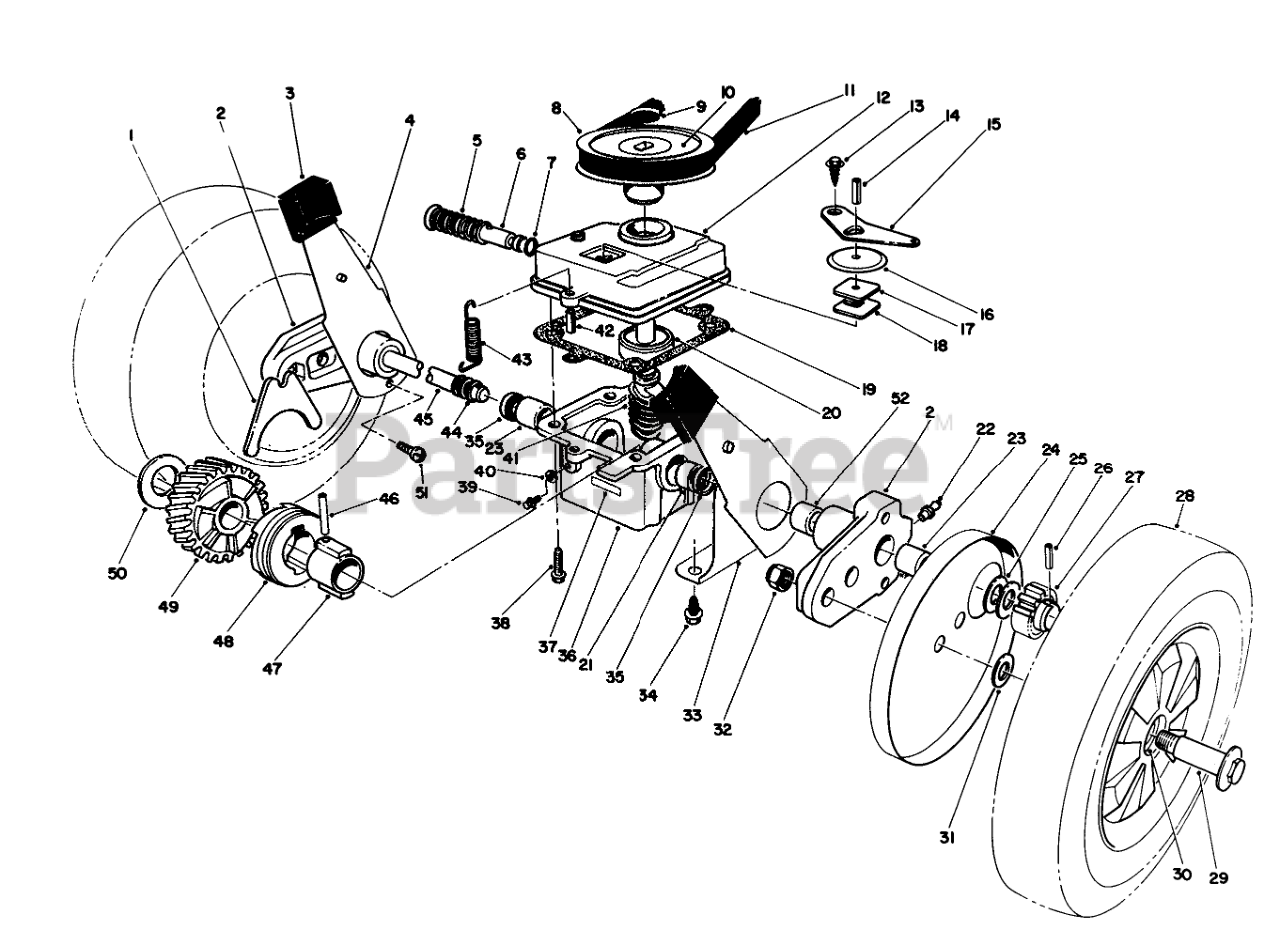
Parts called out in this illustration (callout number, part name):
1	SHIFTER FORK
2	Arm-Pivot (Incl. Ref. #22, 23 & 52)
3	KNOB-ARM
4	SPRING ARM ASSY-FRONT
5	SPRING
6	SHIFTER ROD
7	O-RING
8	PULLEY
9	PUSH-ON 93-3236
10	DECAL
11	V BELT
12	GEAR CASE COVER
13	Screw
14	SPIROL PIN H D
15	SHIFTER ARM
16	DUST COVER
17	DUST FILTER
18	LATCH PLATE
19	GASKET
20	BEARING
21	BUSHING
22	FITTING-GREASE
23	BUSHING
24	Cover-Wheel
25	THRUST WASHER
26	Pin
27	PINION GEAR 15T
28	Wheel, Tire & Gear Assy. (Incl. Ref. #30)
29	BOLT-WHEEL
30	BUSHING
31	WASHER
32	Nut
33	END CAP
34	SCREW-HWHTF
35	SEAL-OIL
36	Gear Case (Incl. Ref. #21, 23, & 35)
37	DECAL
38	Screw
39	NYLON SCREW
40	FILL PLUG GASKET
41	Worm Shaft & Gear (Incl. Ref. #49)
42	3/16 X 1/2 ROLL PIN
43	TENSION SPRING
44	COVER-SHAFT, DRIVE
45	DRIVE SHAFT
46	COIL PIN
47	SLEEVE
48	CLUTCH JAW
49	Helical Gear
50	THRUST WASHER
51	SCREW
52	BUSHING
